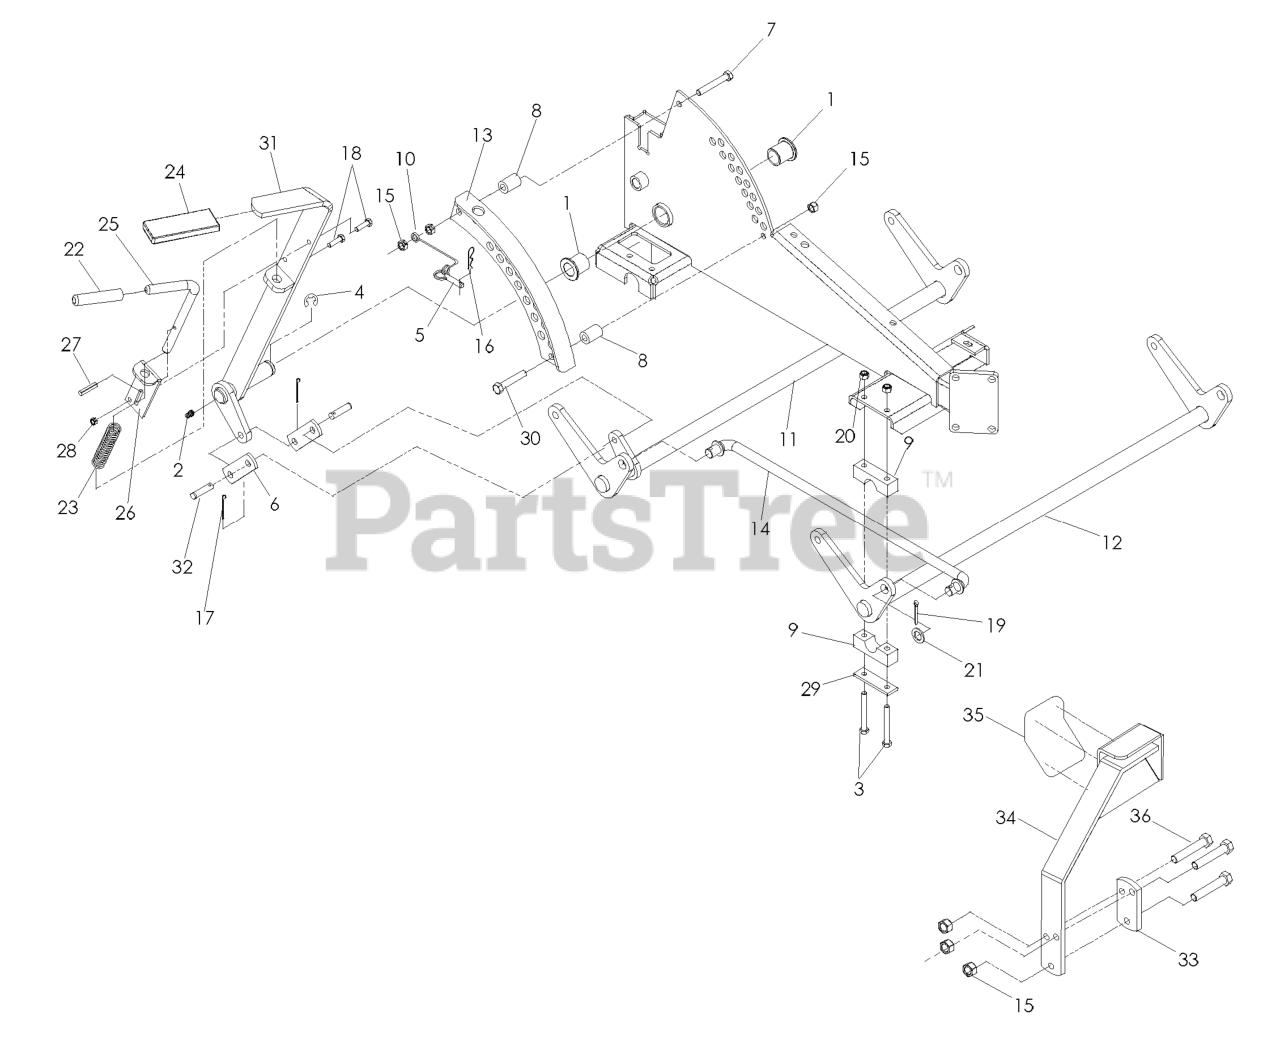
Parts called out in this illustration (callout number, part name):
1	BUSHING, FLANGED
2	ZERK
3	HCS 5/16C X 2-3/4
4	E-RING 7/8
7	SCREW 3/8C X 2 3/4 HEX CAP
8	DECK LIFT SPACER
9	PILLOW BLOCK
11	REAR LIFT SHAFT
12	FRONT LIFT SHAFT
13	ADJUSTMENT PLATE WLDMT
14	CROSS LINK
15	NUT 3/8-16 NYLOC
16	HAIRPIN #4
17	RP_COTTER PIN 1/8 X 3/4
18	HCS 1/4C X 3/4 HCS
19	COTTER PIN
20	NUT 5/16 NYLOC
21	BUSHING
26	PIN MT, UPPER
28	NUT 1/4C CENTER LOCK
29	REINFORCEMENT BAR
30	HCS 3/8C X 2 1/2
31	LIFT LEVER WELDMENT
32	CLEVIS PIN 3/8 X 1 1/8
32	FOOT ASSIST - NOT ON ALL MODELS
33	TIGHTENING PLATE BLK
34	LIFT PEDAL BLK
35	ANTI-SKID PAD
36	HCS 3/8C X 1 1/2
